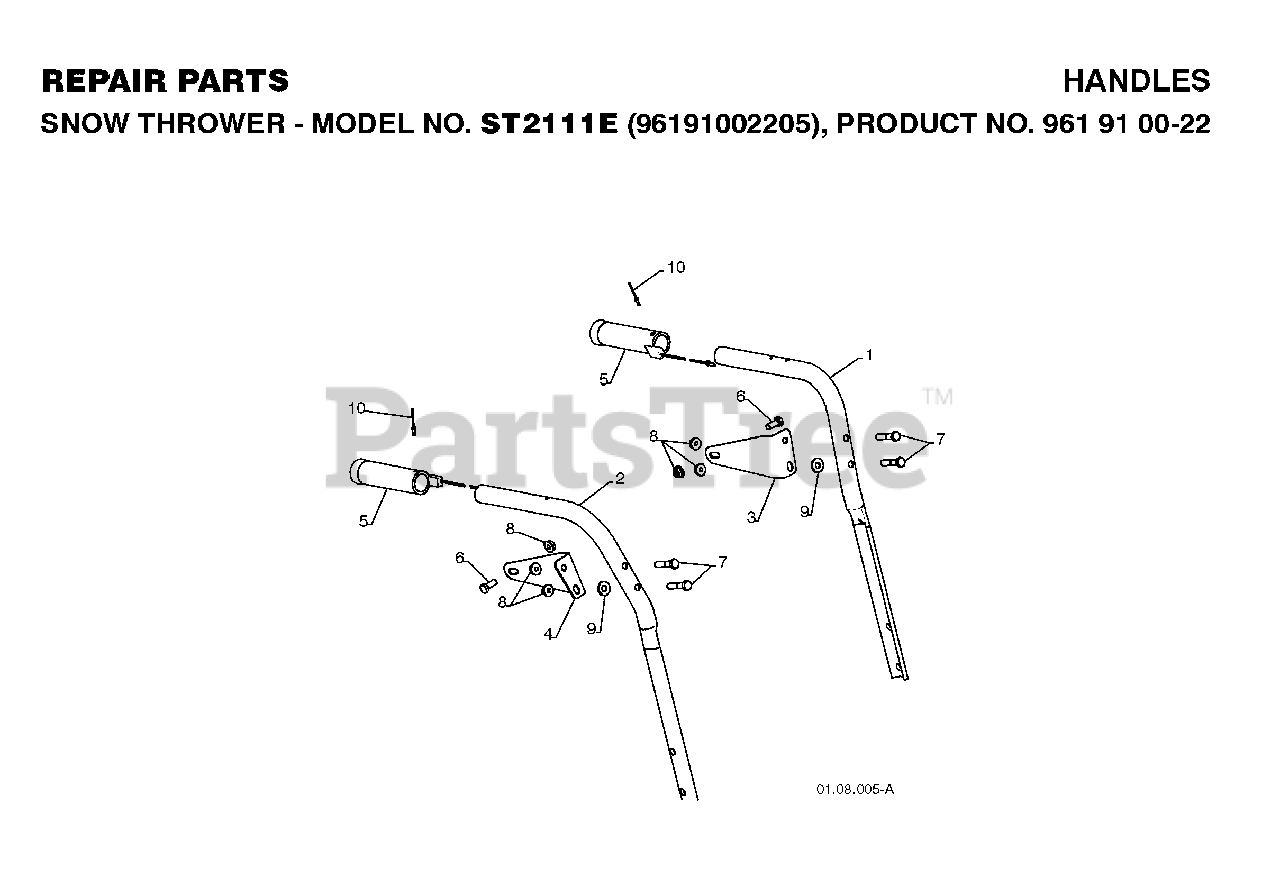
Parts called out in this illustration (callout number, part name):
1	TUBE.HANDLE.PLOW.LH.BLACK
2	TUBE.HANDLE.PLOW.RH.BLACK
3	BRKT.PANEL.LH.INT
4	BRKT.PANEL.RH.INT
5	GRIP HANDLE HEATED
6	BOLT
7	HEX BOLT
8	NUT, LOCK 5/16-18
9	WASHER.20X8.5
10	RIVET.POP.1/8X
